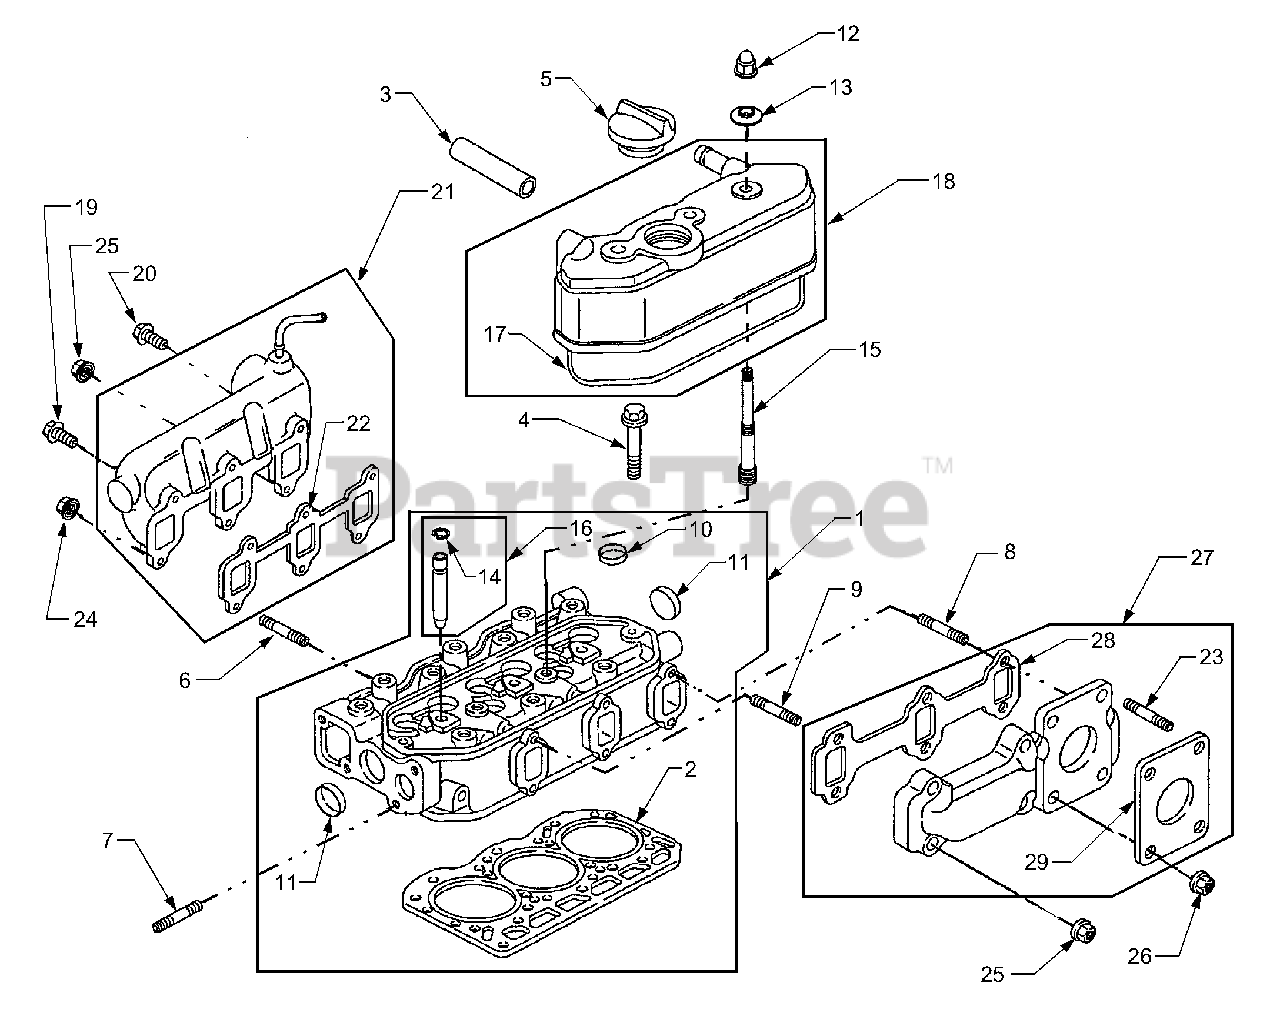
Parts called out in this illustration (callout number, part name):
1	Head, Cylinder
2	Gasket, Cylinder Head
3	Tube, Breather
4	Screw, Metric
5	Cap, Oil Fill
6	Stud, Metric
7	Stud, Metric
8	Stud, Metric
9	Stud, Metric
10	Plug, Welch
11	Plug, Welch
12	Nut, Hex Metric
13	Washer, Sealing
14	Ring, Retainer
15	Stud, Rocker Arm
16	Bushing, Guide
17	Gasket, Rocker Cover
18	Cover, Rocker
19	Screw, Hex, 6mm
20	Screw, Hex, 6mm
21	Manifold, Intake
22	Gasket, Intake Manifold
23	Stud, Exhaust Manifold
24	Nut, Hex Metric
25	Nut, Hex Metric
26	Nut, Hex Metric
27	Manifold, Exhaust
28	Gasket, Exhaust Manifold
29	Gasket, Muffler
